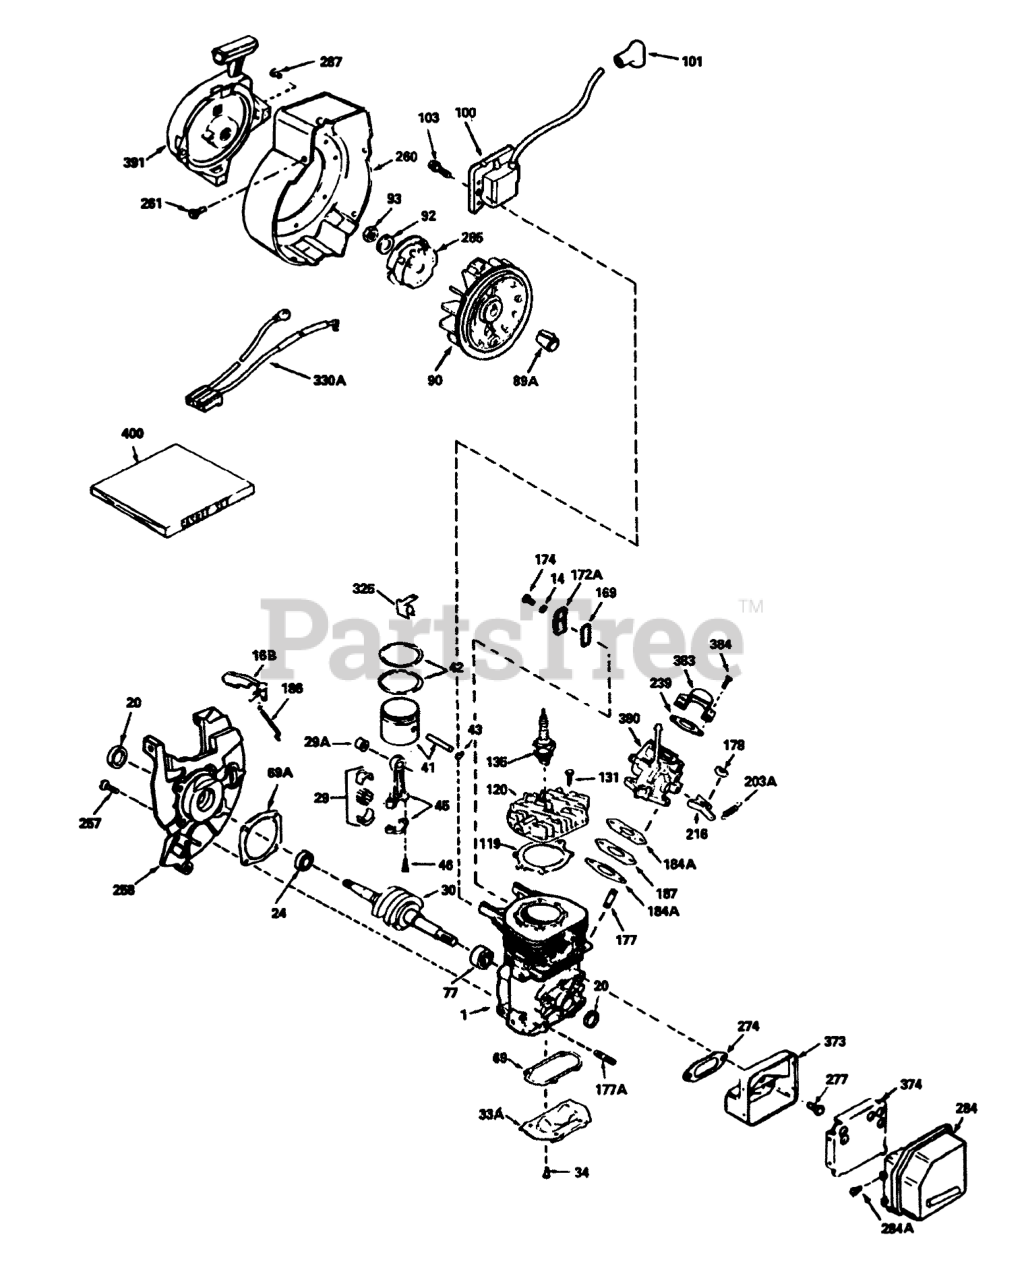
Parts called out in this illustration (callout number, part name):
1	Block Ass-y-Cylinder (Order short block if replacement is required)
14	Washer
16B	Vane-Air
20	Seal-Oil
24	Bearing-Ball
29	Needle Bearing and Liner Set (37 Needles)
29A	Bearing-Cartridge
30	Crankshaft
33A	Plate-Cover
34	Screw (T-25, 10-24 x 1/2)
41	Piston (Incl. Ref. #43)
42	Ring Set
43	Ring-Retaning
45	Rod Assy.-Connecting (Incl. Ref. #3, 3A 3B)
46	Bolt-Rod, Connecting
69	Gasket-Plate, Cover
69A	Gasket-Cover, Cylinder
77	Bearing-Cartridge
89A	Blade (20 inch)
90	Flywheel
92	Washer-Belleville
93	Nut-Flywheel
100	Solid State
101	Cover-Spark Plug
103	Screw
119	Gasket-Head, Cylinder
120	Head-Cylinder
131	Screw (T-30, 1/4-20 x 3/4)
135	Spark Plug-Resistor (R C J 8Y)
169	Cover-Compression, Release
172A	Comp. Release Cover
174	Screw (T-25, 10-24 x 1/2)
178	Locknut
184A	Gasket-Carburetor
186	Link-Governor
187	Spacer
203A	Spring-Governor
216	Lever-Adjusting, Rpm
239	2060A77 WIZARD ROTA
257	Screw (T-30, 1/4-20 x 5/8)
258	Base Assy.-Blower Housing (Incl. Ref. #10)
260	Housing-Blower
261	Screw (1/4-20 x 1/2)
274	Gasket-Exhaust
277	Screw (T-30, 1/4-20 x 5/8)
284	Cover-Muffler
284A	Screw
285	Cup-Starter
287	Rivet-Pop
325	Clip-Wire
330A	Harness-Wire
373	Base-Muffler
374	Baffle-Muffler
380	Carburetor (Incl. Ref. #184A)
383	Baffle-Carburetor
384	Screw
391	Starter-Rewind
400	Gasket Set
